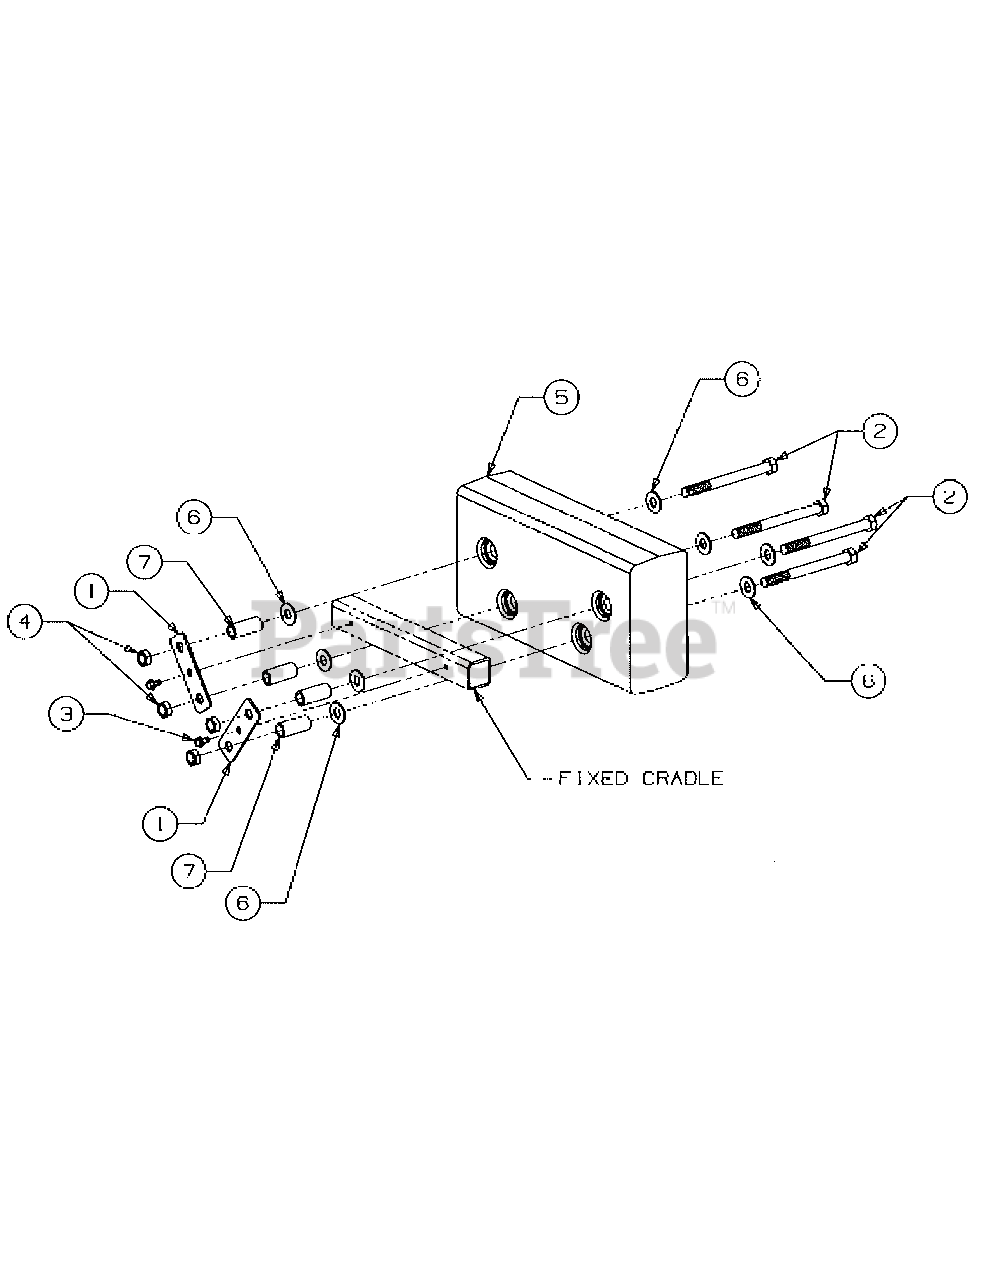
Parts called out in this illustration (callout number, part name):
3	Screw, Hex Wash Hd TT-tap, 1/4-20 x .50
4	Nut, Hex Top Lock Jam, 1/2-20 Gr 5
5	Weight, Counter, 38 Lbs
6	Washer, Flat, .515 x 1.12 x .100 Thk Hdn
7	Spacer, .505 x .75 x 1.75
